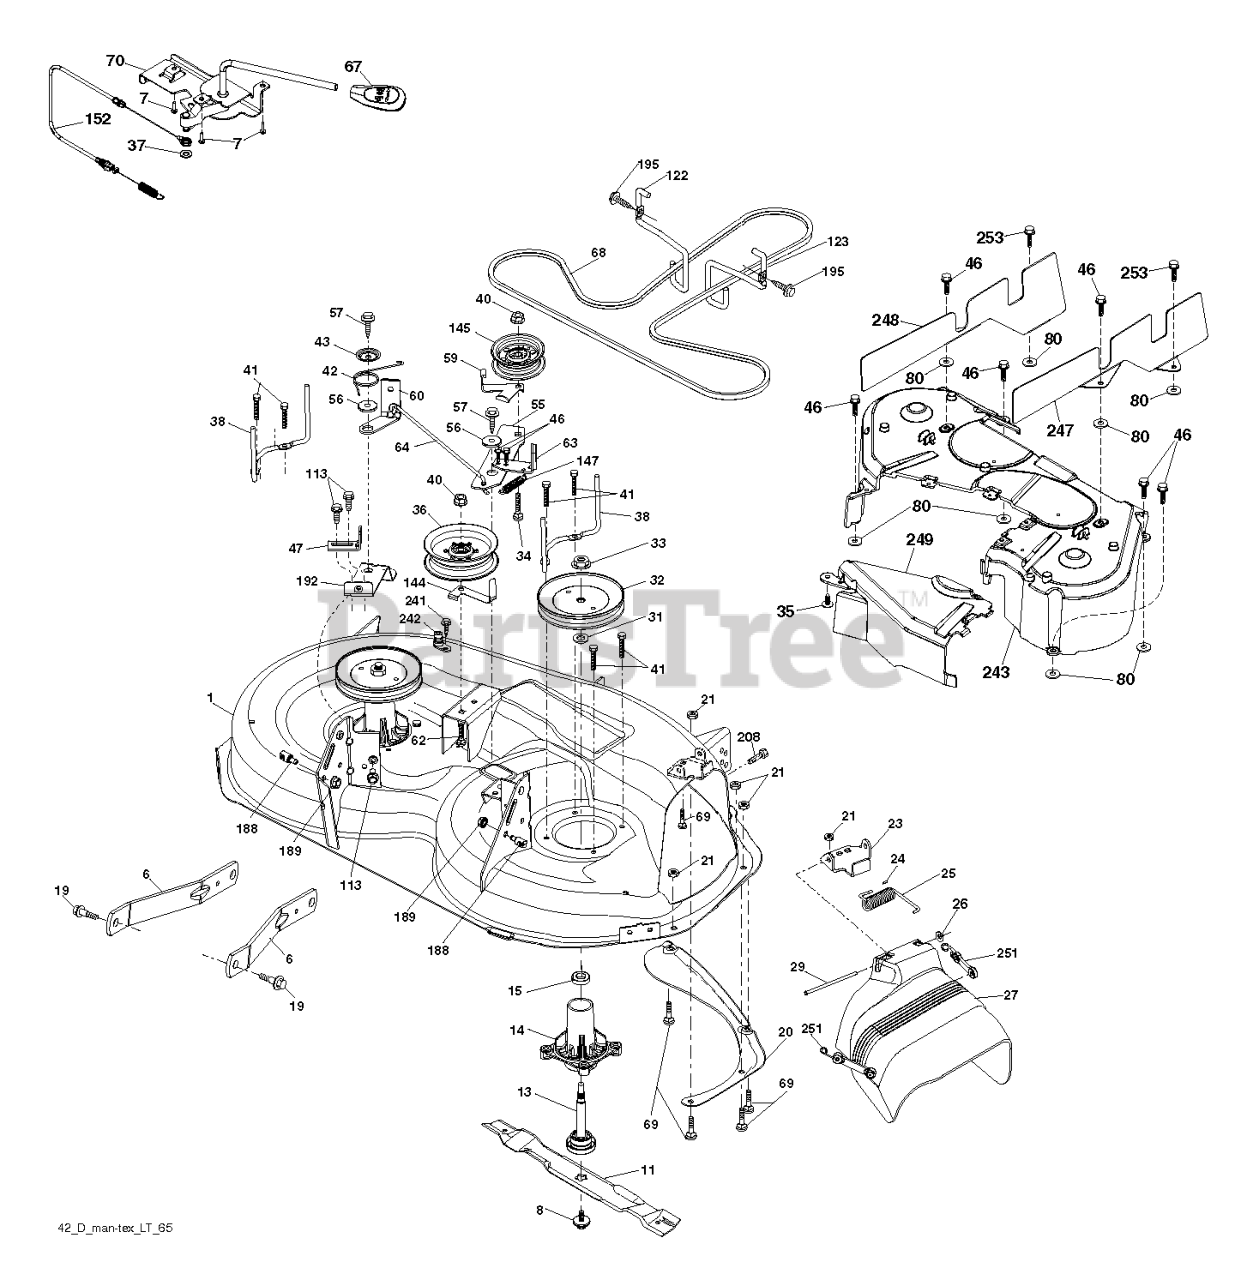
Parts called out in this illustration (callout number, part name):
1	DECK.SVC 42"199911X498
6	ARM.SUSPENSION.MOWER.R
7	SCREW.#10 X 0.750.BOS
8	BOLT.WASHER.ASM.7/16-2
11	42" HI-LIFT BLADE
13	SHAFT.ASM.MDRL.N/GREASE.38
14	RP.HOUSING.MANDREL.4PT.
19	BOLT.SHOULDER
20	BAFFLE.VORTEX
21	LOCKNUT
23	BRKT.DEFLECTOR.38"2005+
24	CAP-SLEEVE LT
25	SPRING.TORSION.DEFLECT
26	NUT PUSH M
27	DEFLECTOR ASM.42"TEX.FRENCH
29	ROD.HINGE
31	WASHER.SPACER.MANDREL
32	PULLEY.MANDREL.5.438.PD
33	NUT.FLANGE.LOCK.TOP
34	BOLT.3/8-16X1.50
35	FASTENER.XMAS.TREE
36	PULLEY.IDLER.2006
37	WASHER
38	KEEPER.BELT.MANDREL.PULLEY
40	NUT LOCK FLG 3/8-16 UNC
41	BOLT.HEX.WASHR.HED.313-18X1.19
42	SPRING.TORSION.BRAKE
43	SRPING.TORSION.RETAINE
46	SCREW.1/4-20X5/8
47	BRKT.CLUTCH.CABLE
55	IDLER.ARM.42"
56	SPACER.RETAINER
57	SCREW 3/8-16X1
59	GUARD, BELT
60	ARM BRAKE MOWER
62	BOLT
63	ARM BRAKE MOWER
64	LINKAGE.BRAKE.ASM.ZINC
67	HANDLE.CLUTCH.CABLE.LT
68	BELT.DECK.DRIVE.42"
69	BOLT
70	CLUTCH.ASM.MANUAL.LT.PRED
80	PALNUT 1/4
113	BOLT.5/16HEX.WHS.HD
122	KEEPER BELT ENGINE LH
123	KEEPER BELT RH
144	KEEPER.BELT.MOWER
145	PULLEY.IDLER.48"PRIMARY
147	RETURN SPRING
152	CABLE.MECHANICAL.CLUTCH
188	STUD.FASTNER.W/ANTI-ROTATE
189	NUT LOCK HEX FLANGE 5/16-18
192	BRKT.BRAKE.STAND.LH.
195	SCREW, 3/8-16X3/4
208	SCREW 3/8-16X1/2
241	SCREW.TT.#10-32X.5.3/8.FLANGE
242	PORT.WASHOUT
243	COVER DECK
247	SHIELD DECK RIGHT
248	SHIELD DECK LEFT
249	COVER CABLE CLUTCH
251	ELASTIC STRAP KIT
253	SCREW
